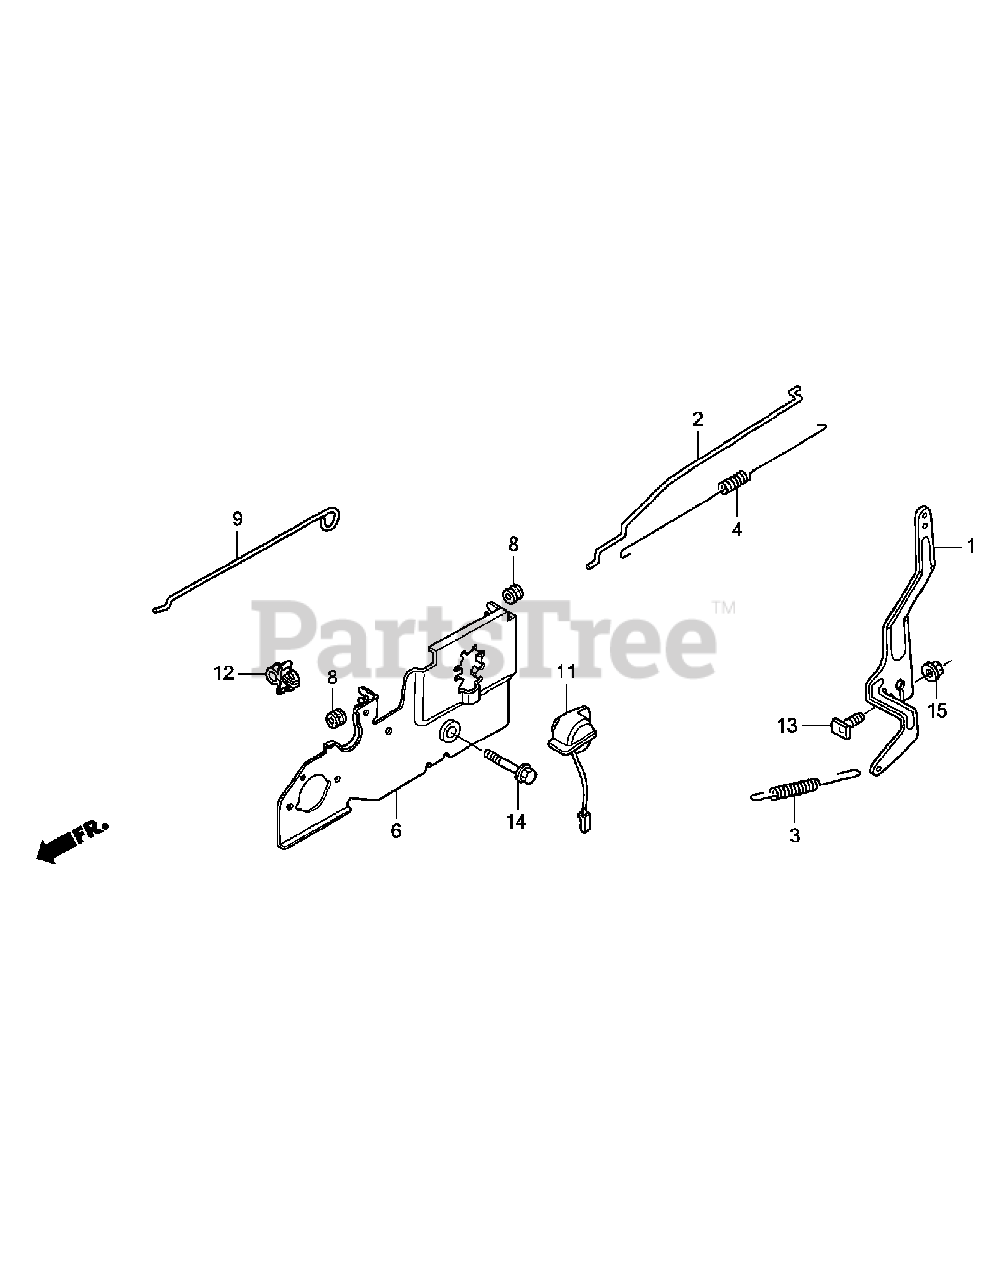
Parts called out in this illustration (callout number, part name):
1	Governor Arm
2	Governor Rod
3	Governor Spring
4	Throttle Return Spring
6	Control Base
8	Choke Rod Grommet
11	Engine Stop Switch Assembly
12	Wire Holder
12	Cable Clip
13	Governor Arm Bolt
14	Flange Bolt, 6 x 45
15	FlangeNut, 6mm
